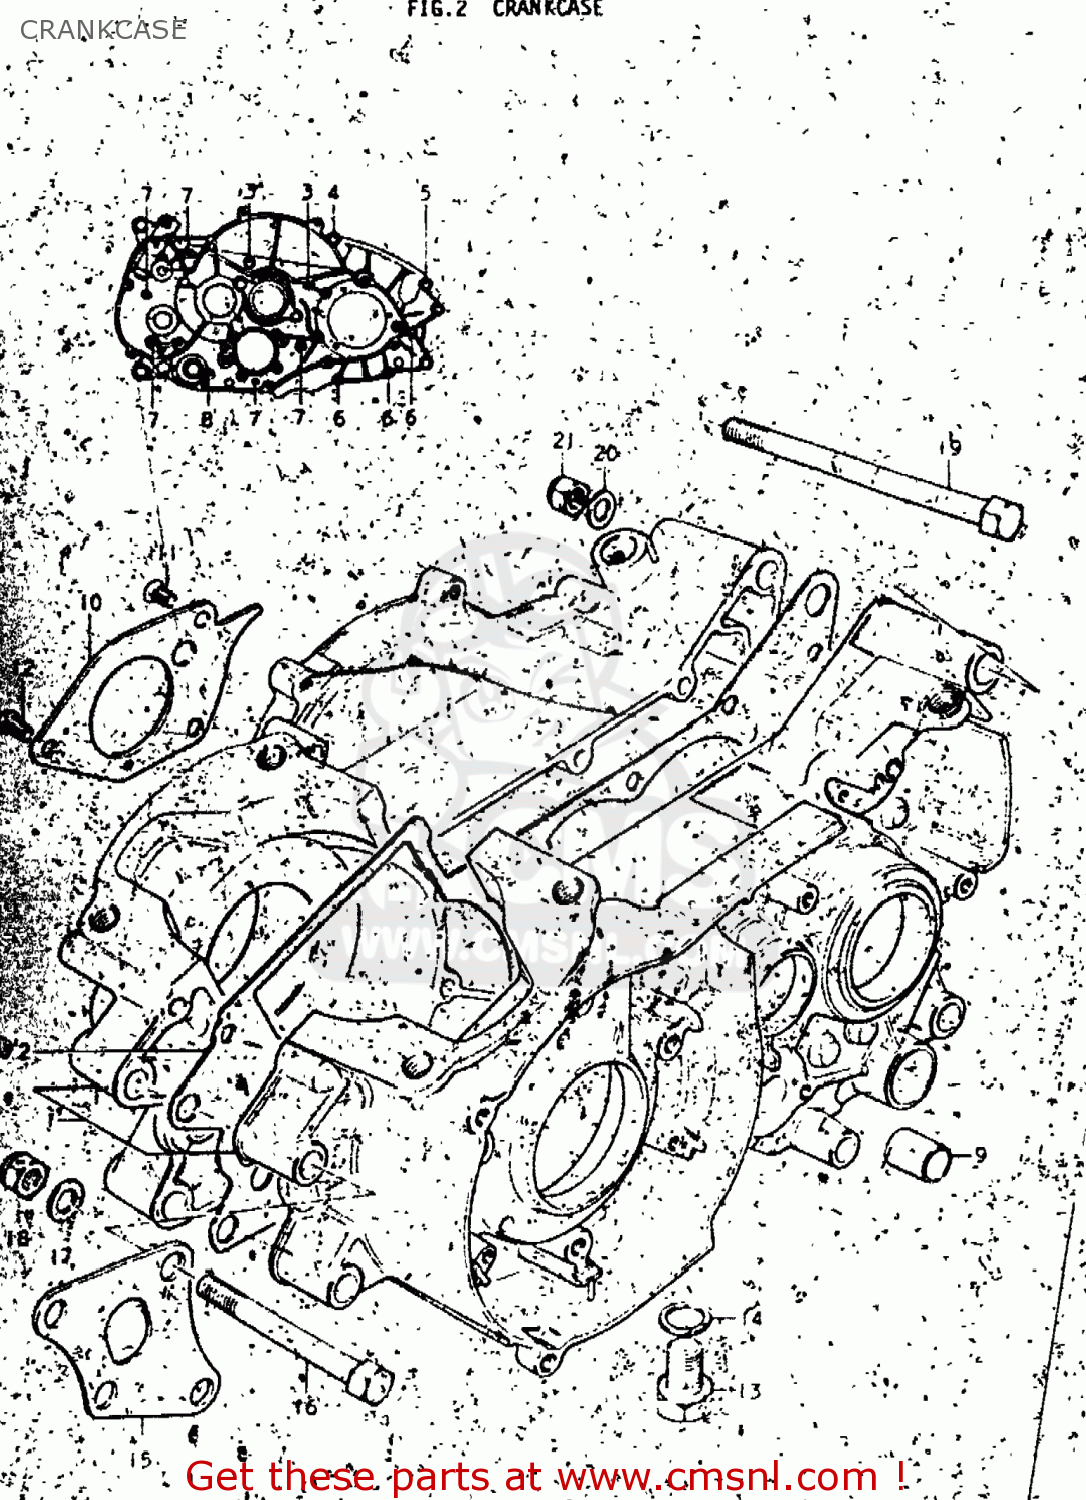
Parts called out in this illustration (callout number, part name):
1	CRANKCASE SET
2	GASKET,CRANKCASE (MCA)
3	SCREW
4	SCREW 6X70
5	SCREW
6	SCREW
7	SCREW (6X45)
8	SCREW (6X35)
9	PIN
10	PLATE,OIL RESERVOIR
11	SCREW
12	SCREW
13	PLUG
14	GASKET(14X19.2X2) (NAS)
15	PLATE,ENGINE MOUNTING
16	HEXAGON BOLT 8X80
17	WASHER
18	NUT
19	BOLT 10X120
20	WASHER
21	NUT
